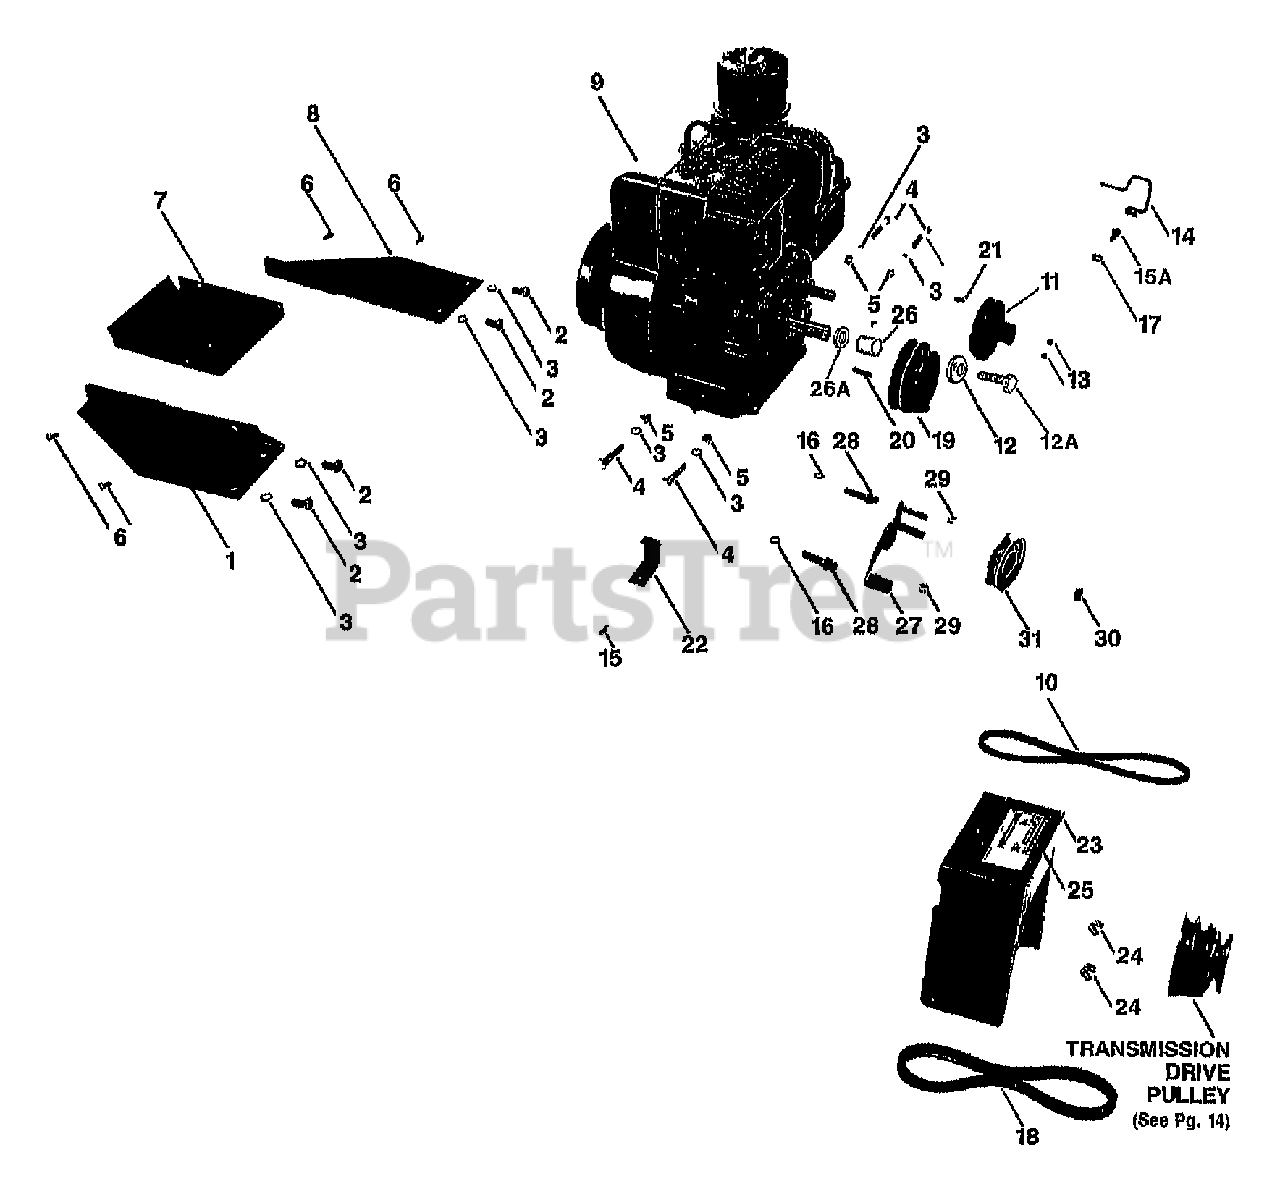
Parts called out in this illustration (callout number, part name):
1	BRKT-ENG LT P4
2	SCR-HHC 5/16-18X.75 GR 5
3	WASHER-LK .312
4	SCR-HH 5/16-18X1.75
5	NUT-HEX 5/16-18
6	SCR-HH SEMS 10-32 X .5 (SEMS - W/PERMANENT WASHER)
7	PAN-ENG BRKT PNT
8	BRKT-ENG RT PNT
9	ENGINE, BRIGGS & STRATTON 5HP,
10	BELT-V (SEE V-BLET SET)
11	PULLEY-ENG MACH
12	WASHER-.827X.331X.098
12A	SCR-HH 5/16-24X.75 G5
13	SCR-SS 1/4-20 X .25
14	GUIDE-BELT FWD
15	SCR-HWH 1/4-20 X .5 STH
15A	SCR-HWH 1/4-20 X .75 STH
16	WASHER-LK .25
17	WASHER-FLAT 1/4 SAE
18	BELT-V GROOVE FWD SMFRAME (SEE V-BELT SET)
19	PULLEY-ENGINE MACH
20	KEY-.188 SQX1.0
21	KEY-WOODRUFF #5
22	GUIDE-BELT REV PNT
23	BELT SHROUD W/DECAL (INCL. 25)
24	NUT-WING/LK 5/16-18
25	DECAL-BELT POSITION
26	SPACER-.755X.937X1.375
26A	SHIM-1.0X.7656X.031 (AS REQUIRED)
27	BRKT-IDLER WELD PNT
28	STUD-5HP (BRIGGS & STRATTON PART)
29	NUT-LK 1/4-20
30	NUT-H/LK 3/8-16
31	IDLER-"V" GROOVE (INTERNAL BUSHING TYPE)
